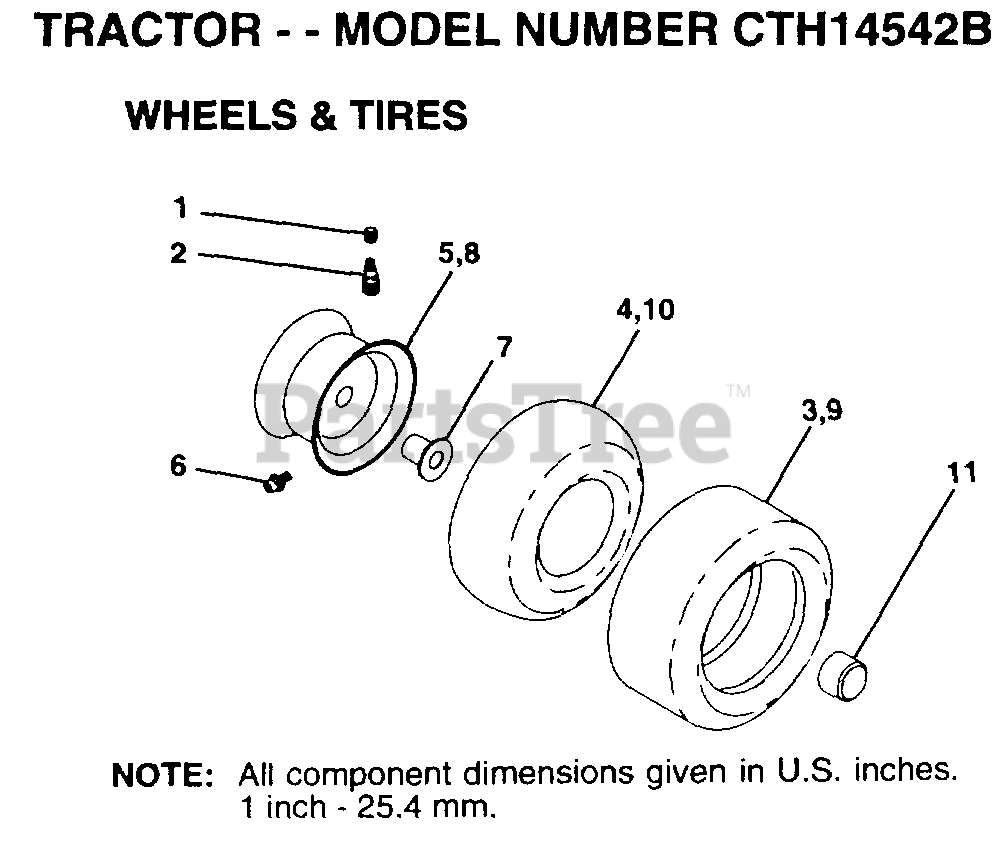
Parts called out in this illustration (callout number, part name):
1	VALVE CAP
2	VALVE STEM LT
4	TUBE.5.3/4.5/6
5	"RIM.ASM.6""FRONT"
6	FITTING LT
7	"FLANGE, BEARING"
8	"RIM.ASM.8""REAR"
10	HEADLAMP BULB
11	HUB CAP
